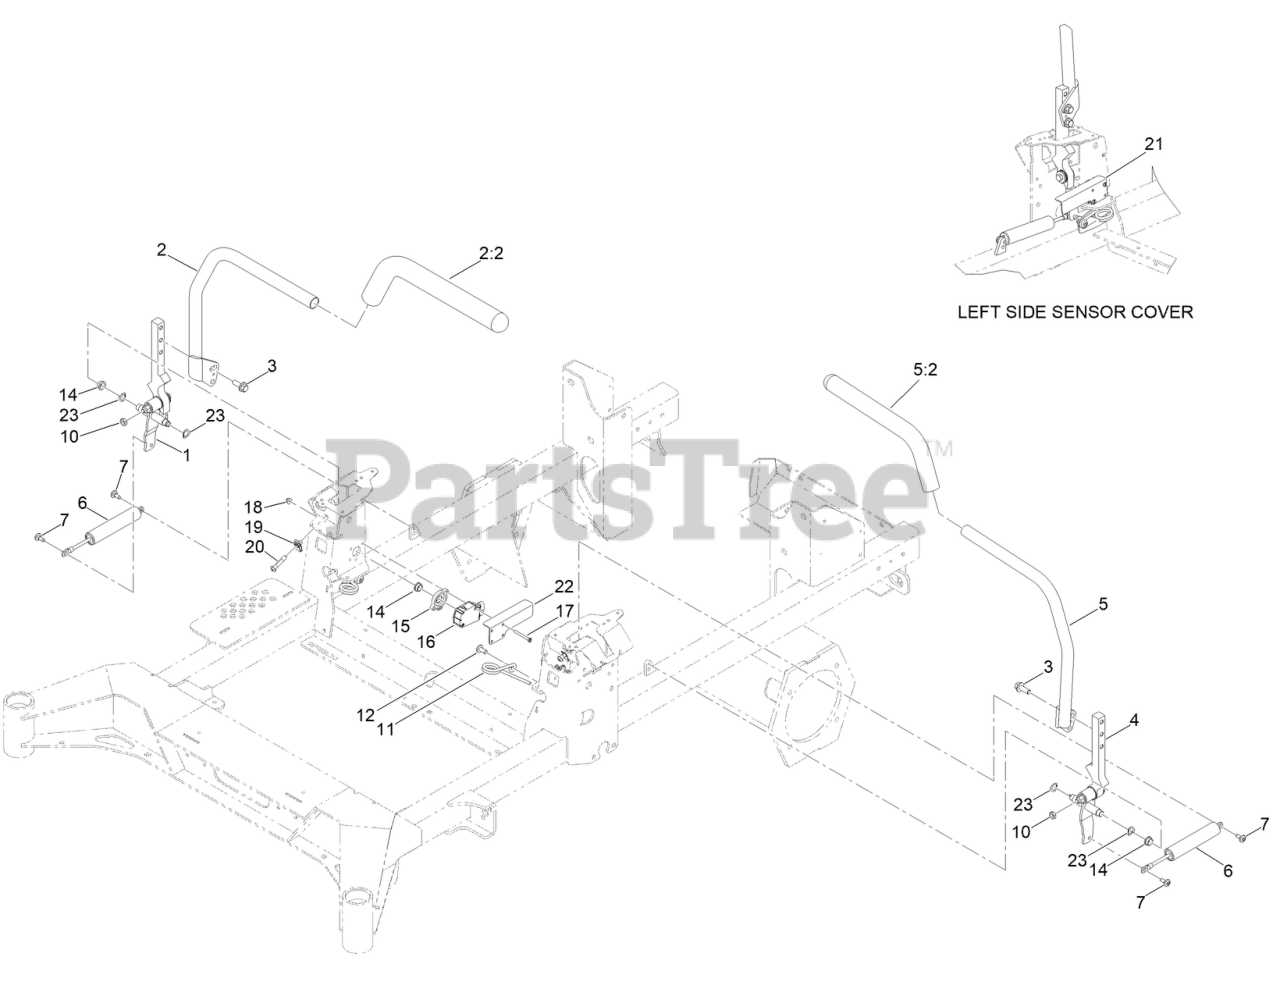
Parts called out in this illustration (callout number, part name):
1	RH MOTION CONTROL ASM
2	HANDLE ASM - RH
2:2	GRIP-CONTROL, LEVER
3	SCREW-HHF
4	LH MOTION CONTROL ASM
5	HANDLE ASM - LH
5:2	GRIP-CONTROL, LEVER
6	DAMPER-NON CAVITATING
7	SCREW-SHOULDER
10	NUT-JAM
11	SPRING-TORSION
14	BUSHING-FLANGE
15	SPACER-SENSOR
16	SENSOR-POSITION
17	SCREW-SHH
18	NUT-HEX FLANGE
20	SCREW-HSBH
21	PLATE-COVER, SENSOR LH
22	PLATE-COVER, SENSOR RH
23	WASHER-SPRING
